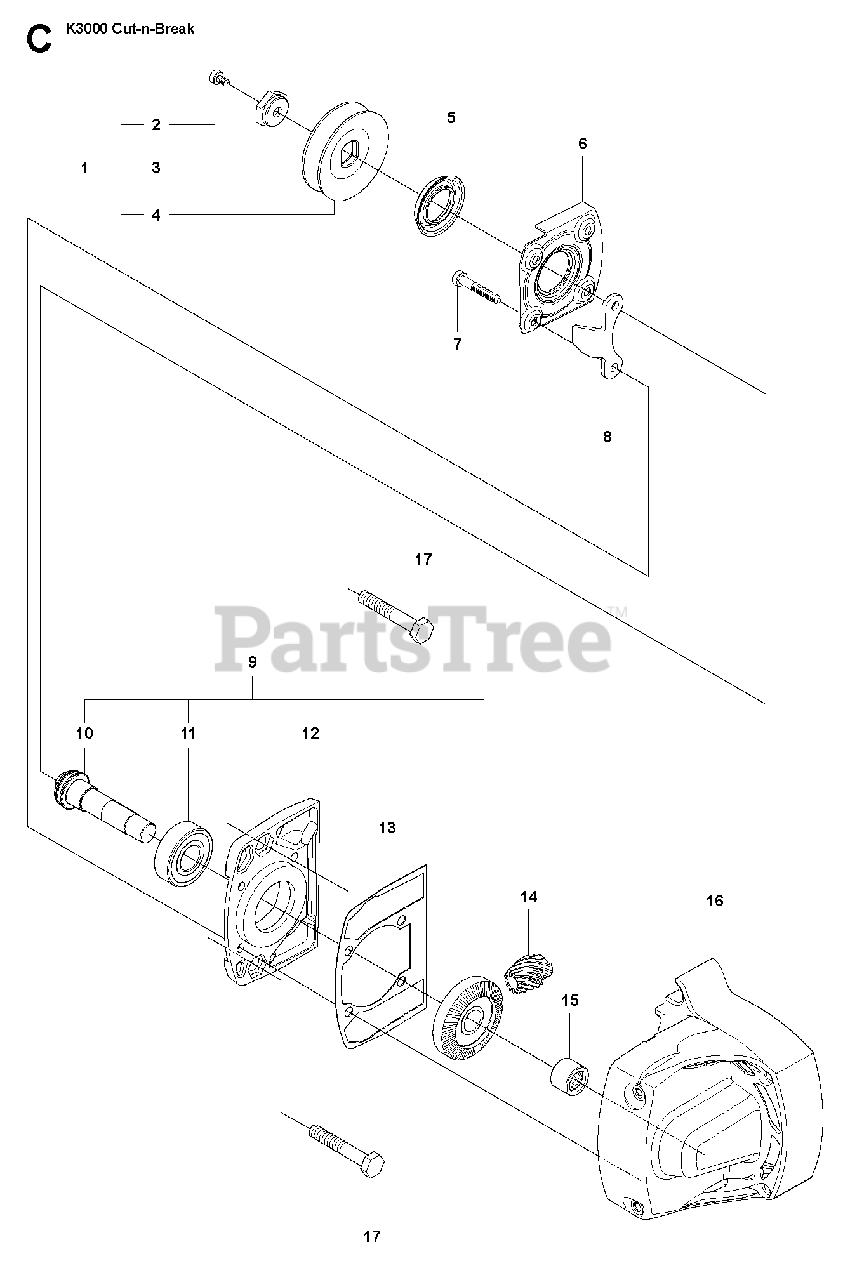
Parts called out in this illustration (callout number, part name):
1	DRIVING PULLEY ASSYIncl. 2 - 4
2	SCREW ITXSCM
7	SCREW ITXSCM
9	GEAR SETIncl. 10 - 12
11	BALL BEARING
15	NEEDLE BEARING
